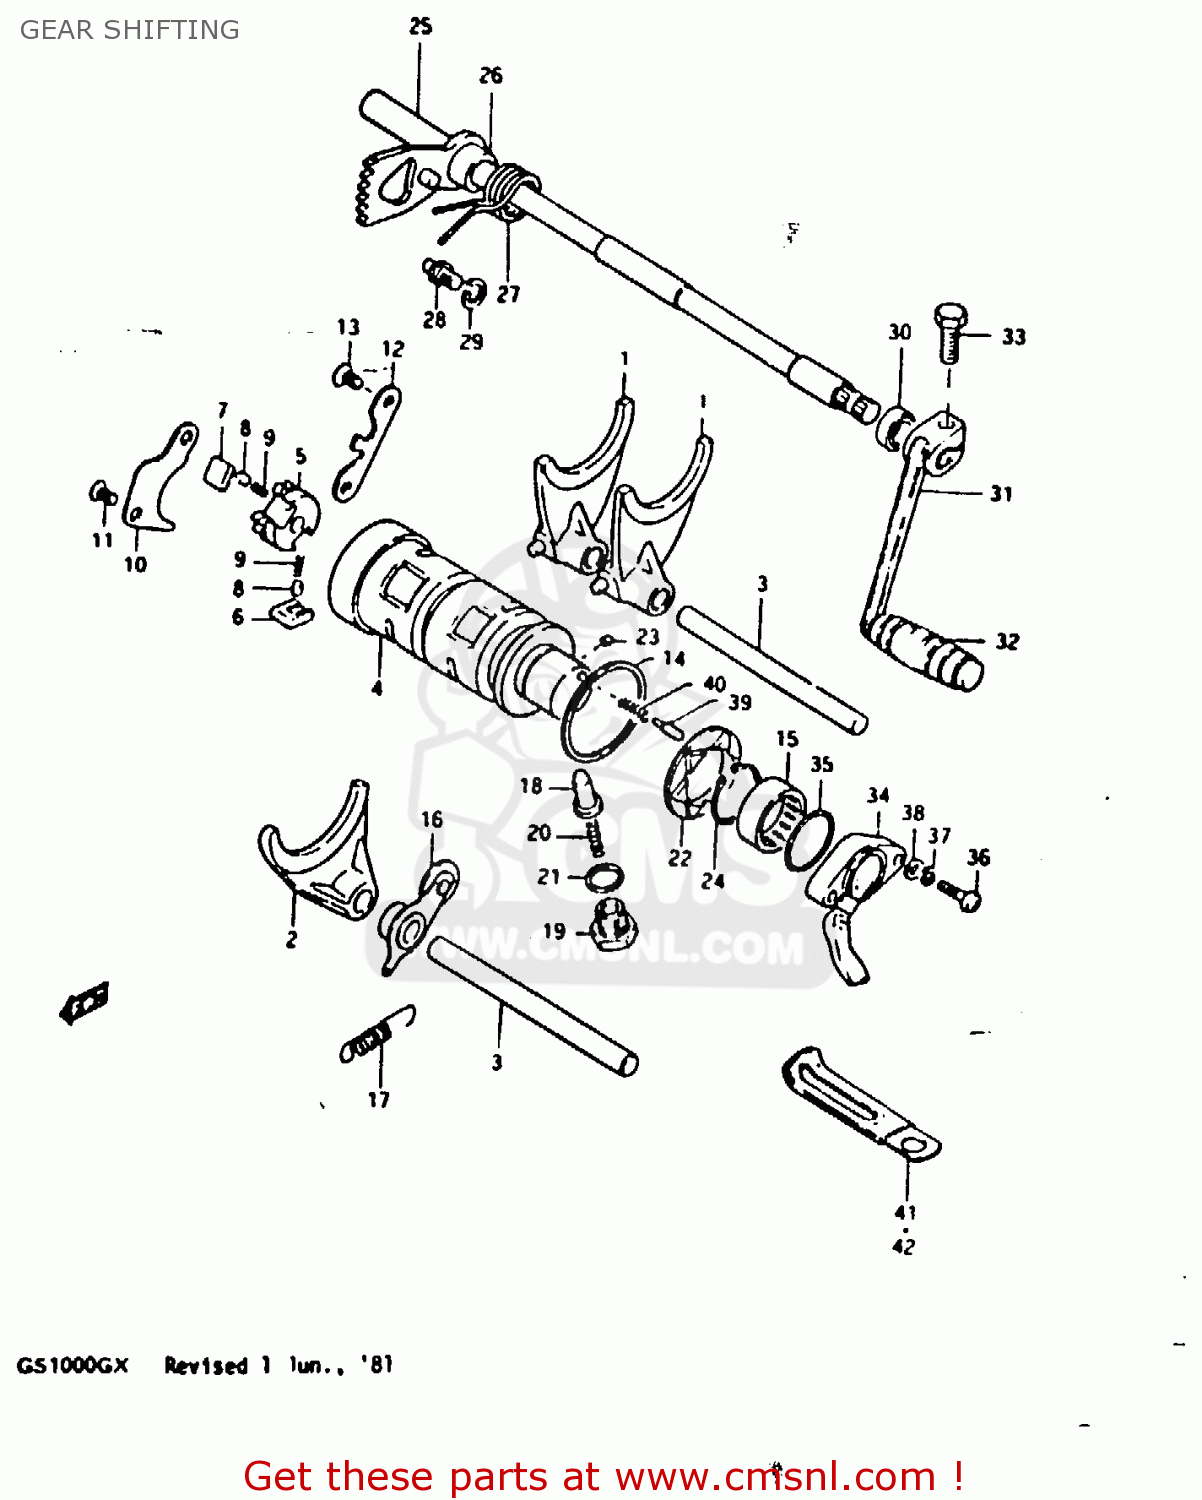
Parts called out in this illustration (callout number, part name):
1	FORK,GEAR SHIFT NO.1
2	FORK,GEAR SHIFT NO.3
3	SHAFT,GEAR SHIFT FORK
4	CAM,GEAR SHIFT
5	RETAINER,GEAR SHIFT CAM
6	PAWL,GEAR SHIFT NO.1
7	PAWL,GEAR SHIFT NO.2
8	PIN(5X8)
9	SPRING
10	LIFTER,GEAR SHIFT PAWL
11	SCREW
12	GUIDE,GEAR SHIFT CAM
13	SCREW
14	WASHER(40X45X1)
15	BEARING(25X32X12)
16	STOPPER,GEAR SHIFTING
17	SPRING
18	STOPPER,GEAR SHIFT CAM NO.2
19	HOLDER,GEAR SHIFT CAM STOP SPR
20	SPRING
21	GASKET(14X19.2X2) (NAS)
22	PLATE,GEAR SHIFT CAM STOPPER
23	PIN 4X6
24	CIRCLIP
25	SHAFT,GEAR SHIFT
26	SPACER (12X20X12)
27	SPRING
28	STOPPER,GEAR SHIFT CAM
29	WASHER
30	OIL SEAL
31	LEVER ASSEMBLY,GEAR SHIFTING
32	RUBBER,GEAR SHIFT PEDAL
33	BOLT
34	TERMINAL BASE ASSY,GEAR SHIFT
35	O-RING (D:2.4 ID:26.2)
36	SCREW 5X20
37	LOCK WASHER
38	WASHER
39	PIN(5X15.5)
40	SPRING
41	CLAMP L:35
42	CLAMP
